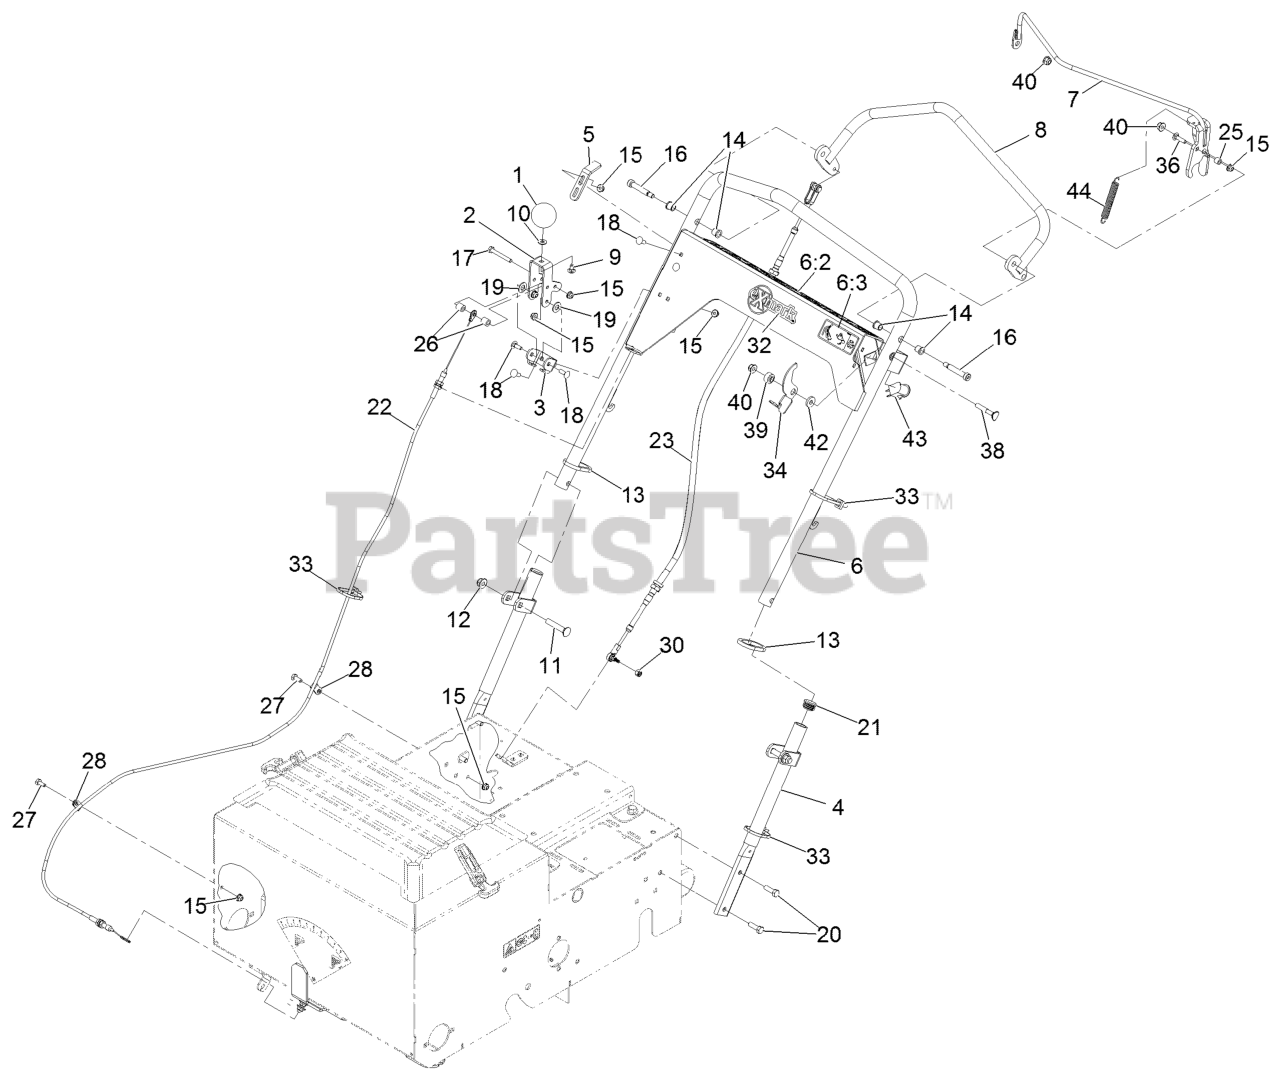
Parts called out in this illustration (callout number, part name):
1	KNOB-RATE, FLOW
2	LEVER-ADJUST, FLOW
3	BRACKET-ADJUST, FLOW
4	HANDLE-LOWER
5	BRACKET-ADJUST, DRIVE
6:2	DECAL-CONTROL PANEL, SEED
6:3	DECAL-SAFETY LATCH
7	BAIL-CLUTCH
8	HANDLE-DRIVE
9	SCREW-CARR
10	WASHER-FLAT
11	SCREW-HH
12	NUT-HF, NI
13	RING-HANDLE LOCK
14	BEARING
16	SCREW-SHOULDER
17	SCREW-HH
18	BOLT-CARR
19	WASHER-PLAIN
20	SCREW-HH
22	CABLE-FLOW, SEED
23	CABLE-PUSH PULL
27	SCREW-HH
28	CLAMP-R
30	NUT-LOCK
33	TIE-CABLE
34	LATCH-BAIL
36	SCREW-CARR
39	BUSHING-STEPPED
40	NUT-HF, NI
42	WASHER-FLAT
43	SWITCH-BAIL
